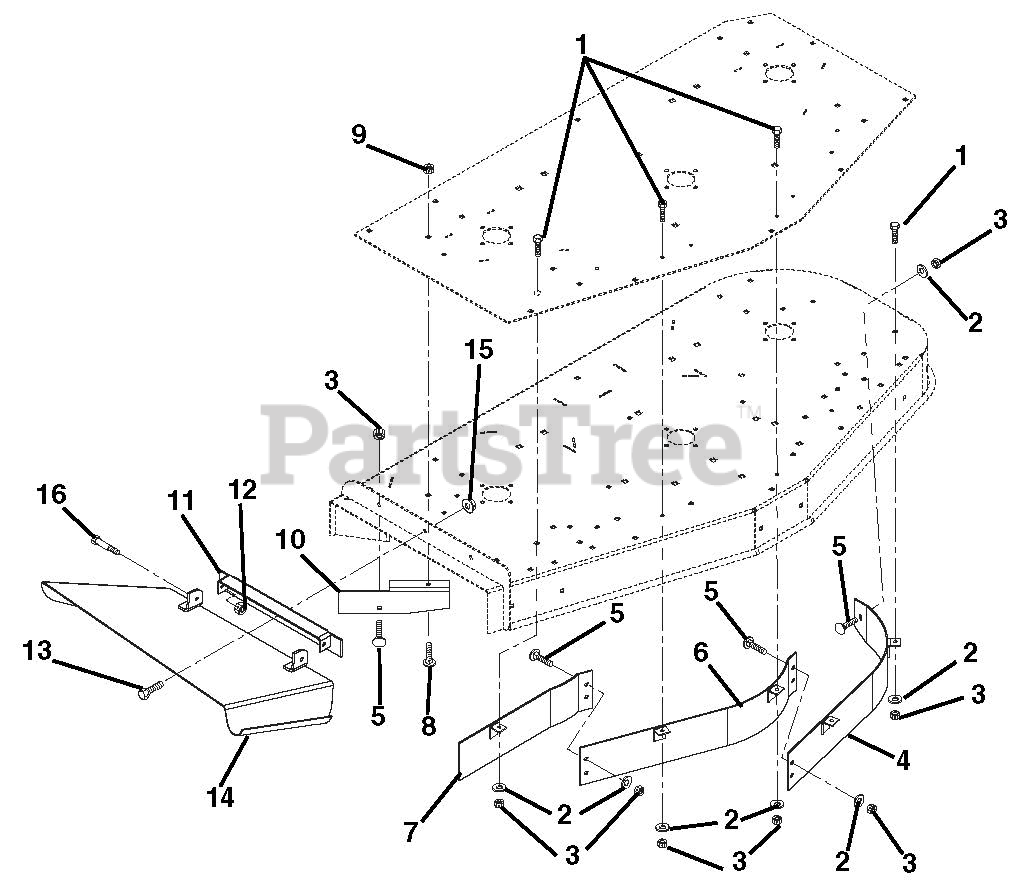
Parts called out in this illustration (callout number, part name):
1	BLT-HEX .31-18X1.00 GR5 YWZC
2	WSHR-FL-STL.312X.734X.065 YWZ
3	NUT-LK-NYL .312-18 YWZC
4	BAFFLE - LEFT FRONT - 60"
4	BAFFLE - LEFT FRONT - 72"
5	BLT-RDHDSQNK .31-18X.75 G5YZ
6	BAFFLE - CENTER FRONT - 60"
6	BAFFLE - CENTER FRONT - 72"
7	BAFFLE - RIGHT FRONT - 60"
7	BAFFLE - RIGHT FRONT - 72"
8	BLT-RDHDSQNK .38-16X1.00 G5YZ
9	NUT-LK-NYL .38-16 YWZC
10	DEFLECTOR, 60" (BLACK)
10	DEFLECTOR, 72"
11	WLDMT. DISCH. CHUTE BRKT (RED)
12	NUT-LK-CTR .38-16 YWZC
13	BLT-HEX .38-16X1.00 GR5 YWZC
14	WMT, DISCHARGE CHUTE 60"
14	WLDMT, DISCHARGE CHUTE 72"
15	NUT-SPNLK-FLG .375-16 YWZC
16	BLT-SHLDR .38-16X.38 SKH
